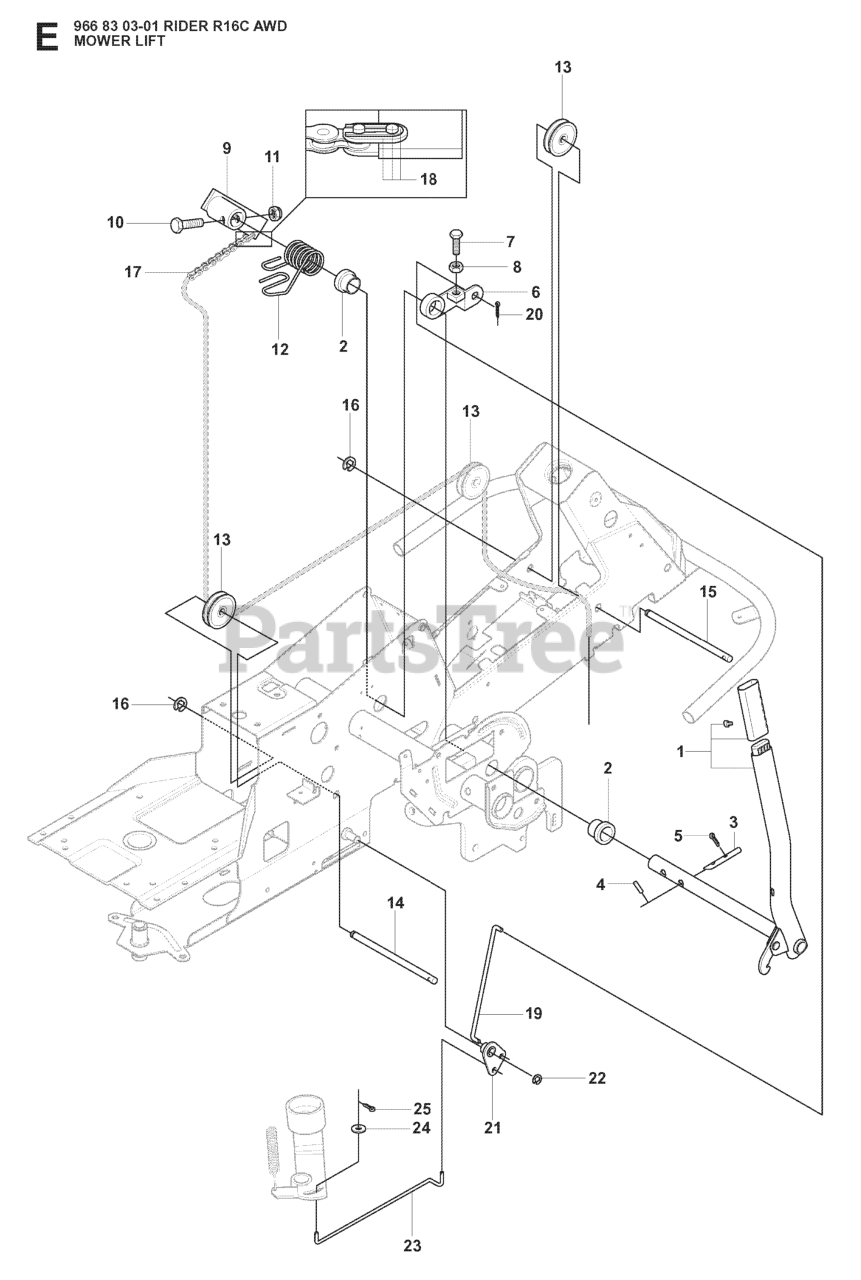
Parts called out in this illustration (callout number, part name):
1	LIFTING LEVER ASSY
2	BEARING FLANGE
3	RP PIN
6	LEVER CLUTCH
8	NUT
9	LIFTING ARM
19	CONNECTION ROD
22	RETAINING RING
23	CONNECTION ROD
